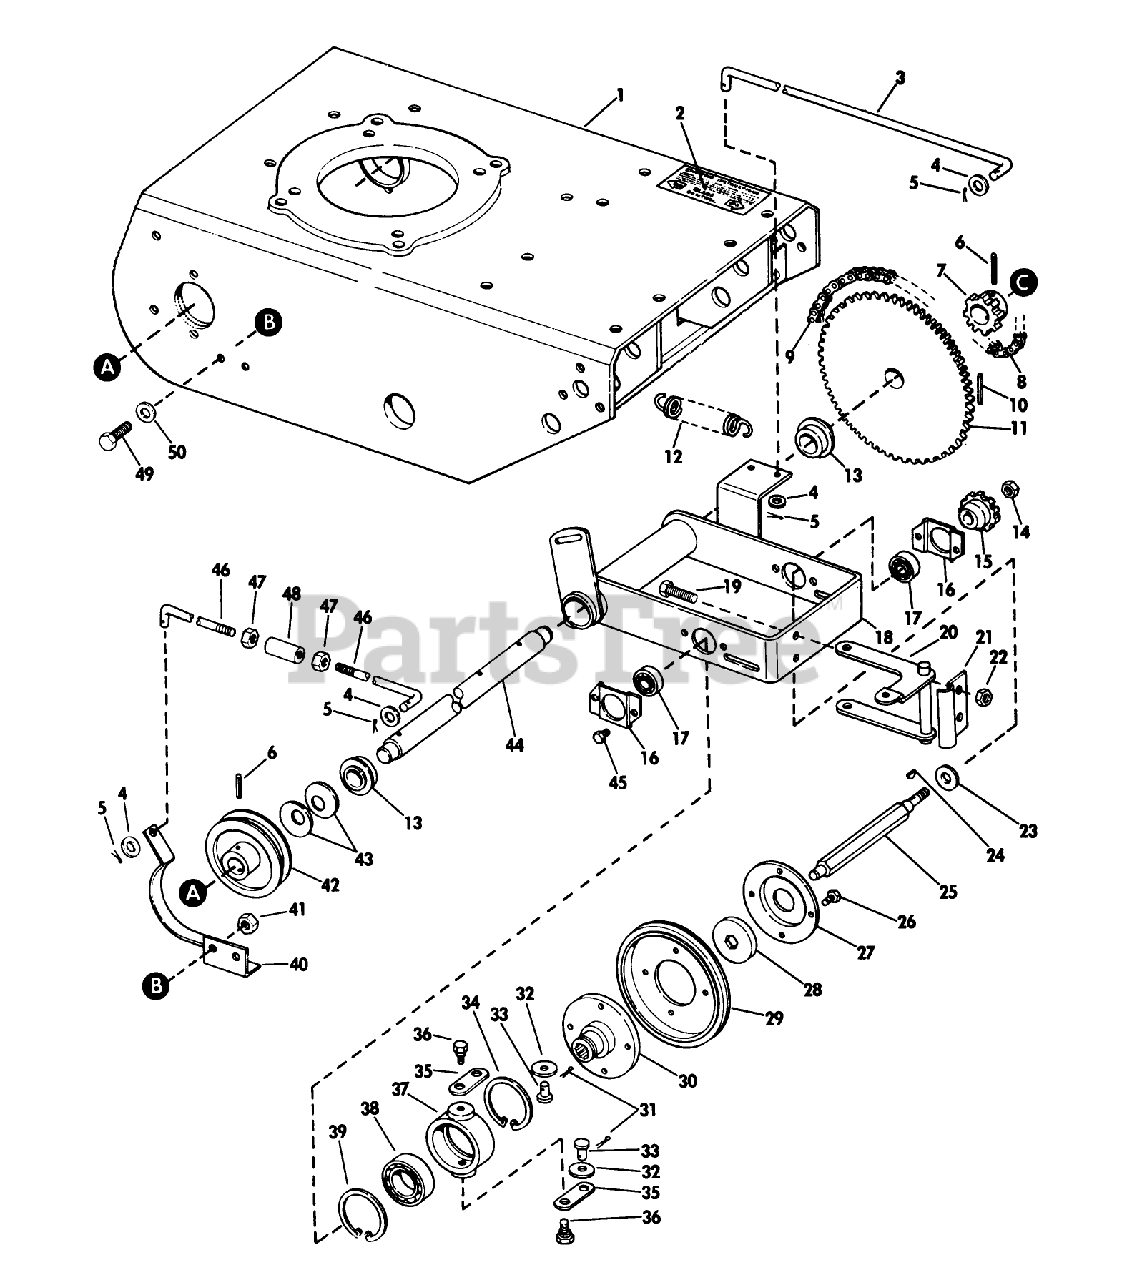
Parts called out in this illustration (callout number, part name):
14	LOCKNUT
29	DRIVE WHEEL
47	STOP NUT
